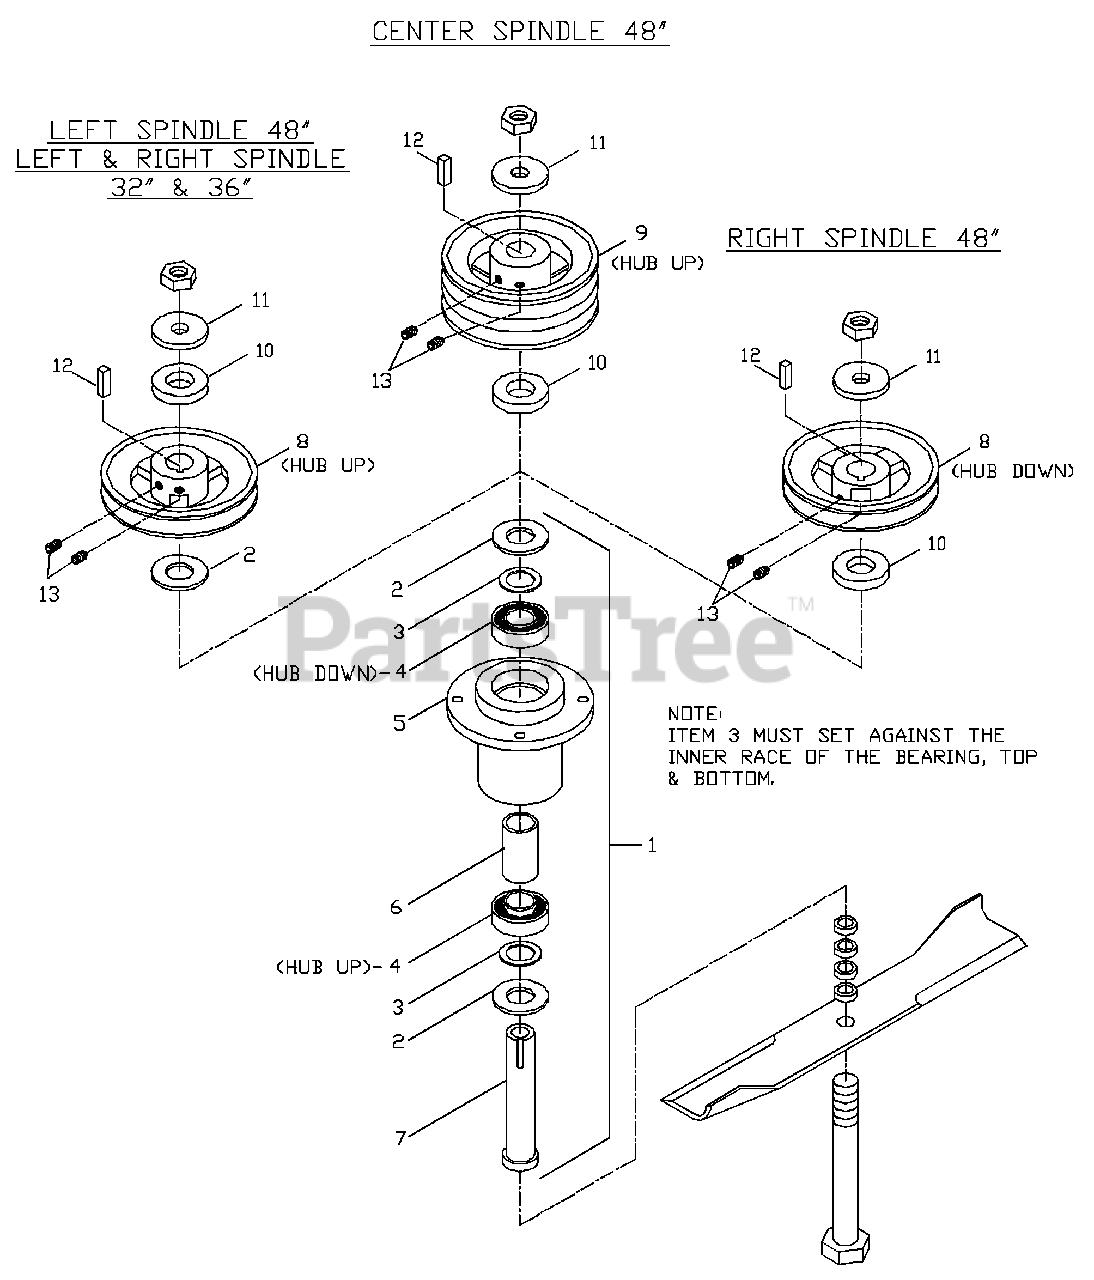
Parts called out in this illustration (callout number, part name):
1	CUTTER HOUSING ASM.
2	MACH. BUSING 10GA.
3	MACH. BUSING 18GA.
4	BEARING
9	DOUBLE PULLEY
10	3/8" SPACER
11	1/4" SPACER
12	KEY 1/4 SQ. X 1 1/8"
13	5/16 NYLOC SETSCREW
